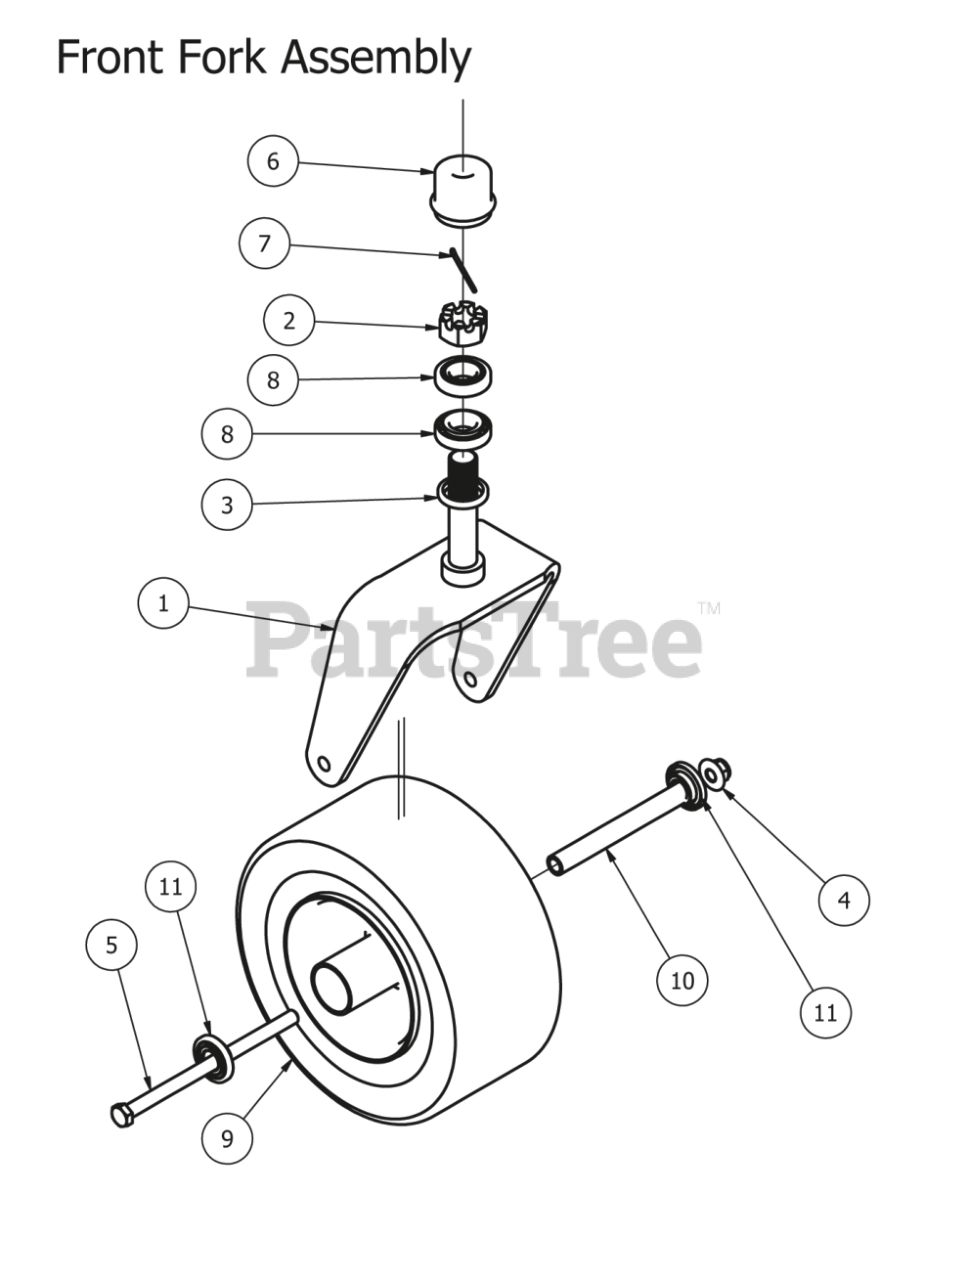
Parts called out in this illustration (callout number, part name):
1	Front Fork
2	1" Fine Threaded Castle Nut
4	1/2-13 Nylon Flange Nut-Orange
5	1/2" x 9" Bolt
6	Dust Cover
7	1/8x2-1/4 cotter pin Zinc
9	Tire and wheel assembly
10	Front Wheel Spacer
11	Wheel Bearing
